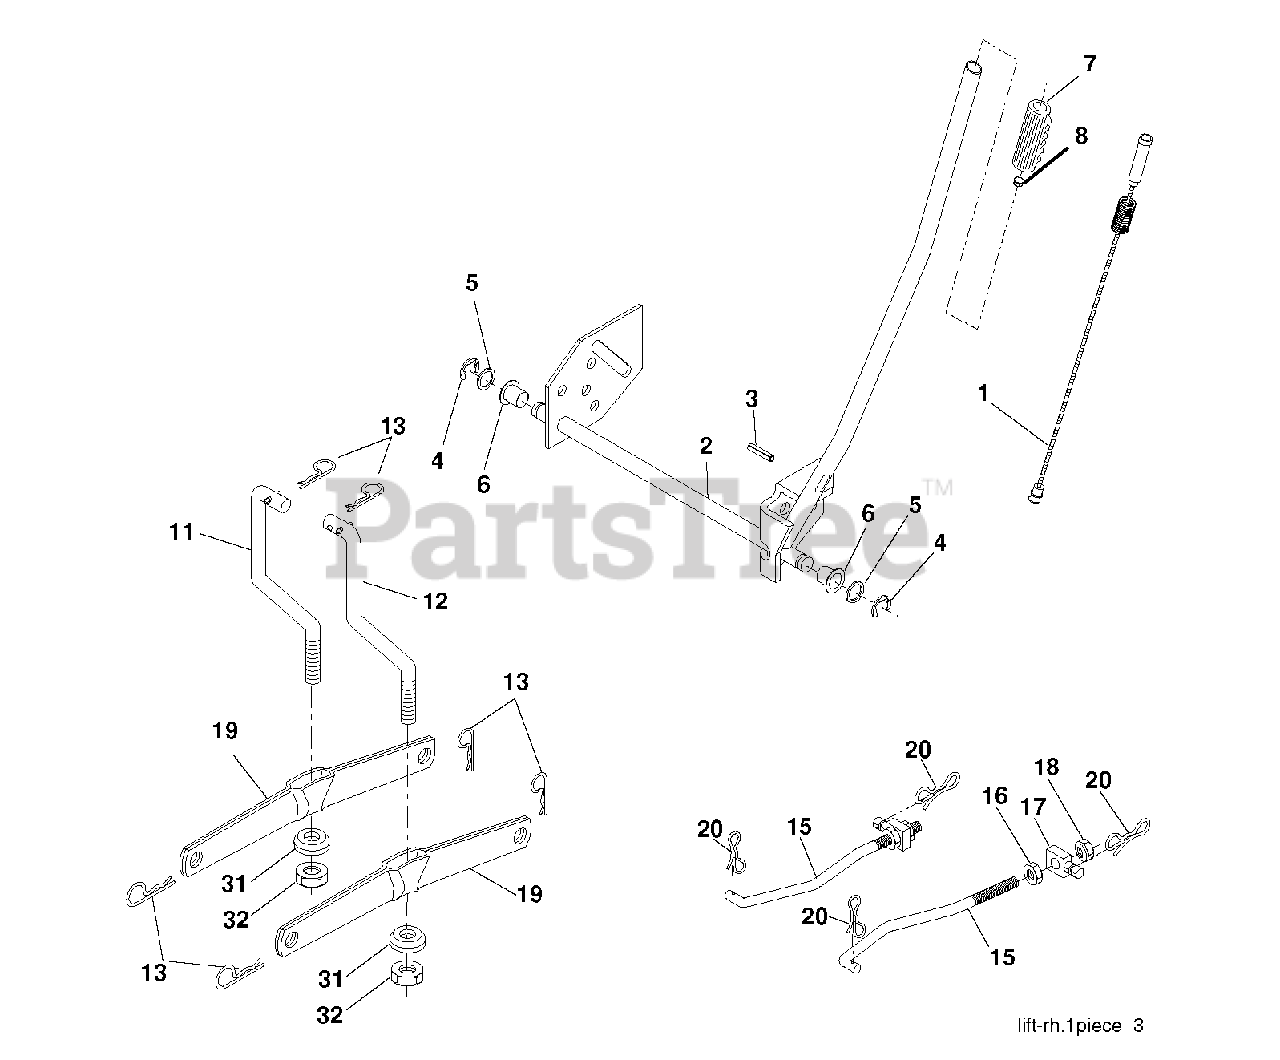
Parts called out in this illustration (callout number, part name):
1	PLUNGER.ASM.LIFT.LVR.B*SUBS/2*
2	SHAFT.ASM.LIFT.YT
3	Groove Pin, 5/16
4	RETAINING RING LT
6	BEARING.NYLON
7	GRIP
8	PLUNGER BUT KIT
11	LINK
12	LINK
13	RETAINER-SPRNG RB
15	LINK.SUSPENSION.FRONT
16	NUT
18	NUT
19	ARM.REAR.SUSPENSION
20	PIN.COTTER.7/16.BOW TI
31	BEARING.PIVOT.LIFT
32	NUT CROWNLOCK 3/8-24
